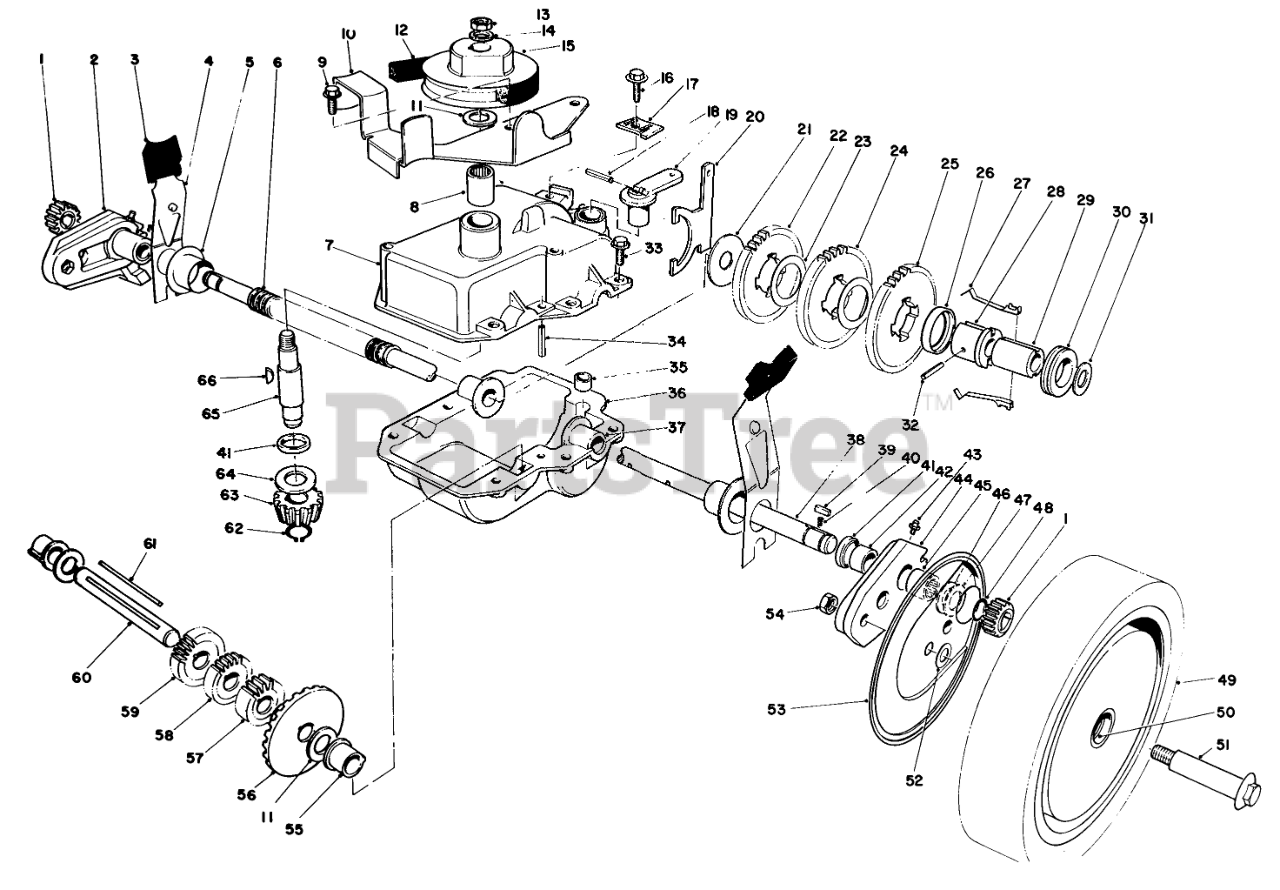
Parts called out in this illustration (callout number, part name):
1	GEAR-PINION
2	Pivot Arm Assembly-R.H. (Incl. Ref. #41-43 & 45)
3	KNOB-ARM
4	SPRING ARM ASM SP
5	CAP-END
6	CONDUIT-CONVOLUTED, SPLIT
7	Upper Case
8	BEARING
9	SCREW
10	BELT GUIDE BRKTB
11	WASHER-THRUST
12	V-BELT
13	NUT-LOCK
14	WASHER-FLAT
15	PULLEY
16	SCREW-HWHTF
17	Cable Clamp
18	PIN-COIL
19	LEVER-SHIFT
20	Shift Yoke
21	WASHER
22	GEAR-38T
23	WASHER
24	GEAR-42T
26	KEY RETAINER
27	KEY-SHIFT
28	Body-Sleeve
29	SLEEVE
30	COLLAR-SHIFT
31	WASHER-PLAIN
32	PIN-SPRING
33	SCREW-HWHTF
34	ROLL PIN 3/16 X 1 IN
35	BUSHING-YOKE
36	LOWER GEAR CASE CAST
37	Bushing-Output Shaft
38	Output Shaft
39	KEY RECTANGULAR
40	SPRING-COMPRESSION
42	BUSHING
43	FITTING-GREASE
44	Pivot Arm Assembly-L.H. (Incl. Ref. #41-43 & 45)
45	BEARING-ROLLER
46	INNER THRUST WASHER
47	WASHER-THRUST, OUTER
48	RING-RETAINING
49	Wheel, Tire & Gear Assembly (Incl. Ref. #50)
50	BUSHING
51	WHEEL BOLT
52	WASHER
53	WHEEL COVER
54	NUT-LOCK
55	BUSHING
56	BEVEL GEAR
57	GEAR-12T
58	GEAR-14T
59	GEAR-18T
60	INTERMEDIATE SHAFT
61	Key Square
62	RING-RETAINING
63	PINION-BEVEL
64	WASHER-THRUST
65	INPUT SHAFT
66	KEY-WOODRUFF
